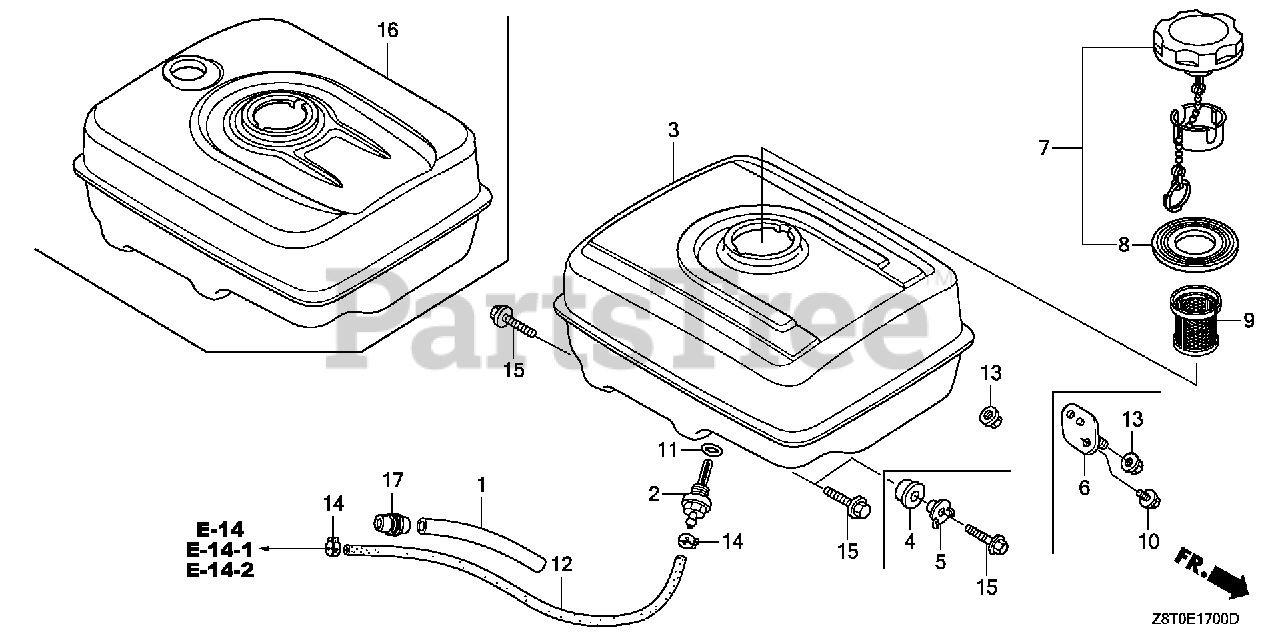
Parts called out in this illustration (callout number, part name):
1	RUBBER, SUPPORTER (107MM)
2	JOINT, FUEL TANK
7	CAP, FUEL FILLER
8	GASKET, FUEL FILLER CAP (39X62X3) (RADICON)
11	O-RING (13.5X1.5) (ARAI)
11	O-RING (14MM) (NOK)
12	TUBE, FUEL (4.5X235) (FKM)
13	NUT, FLANGE (8MM)
14	CLAMP, TUBE (D8)
15	BOLT, FLANGE (8X25)
16	TANK, FUEL *NH31* (MCKINLEY WHITE)
16	TANK, FUEL *NH1* (BLACK)
